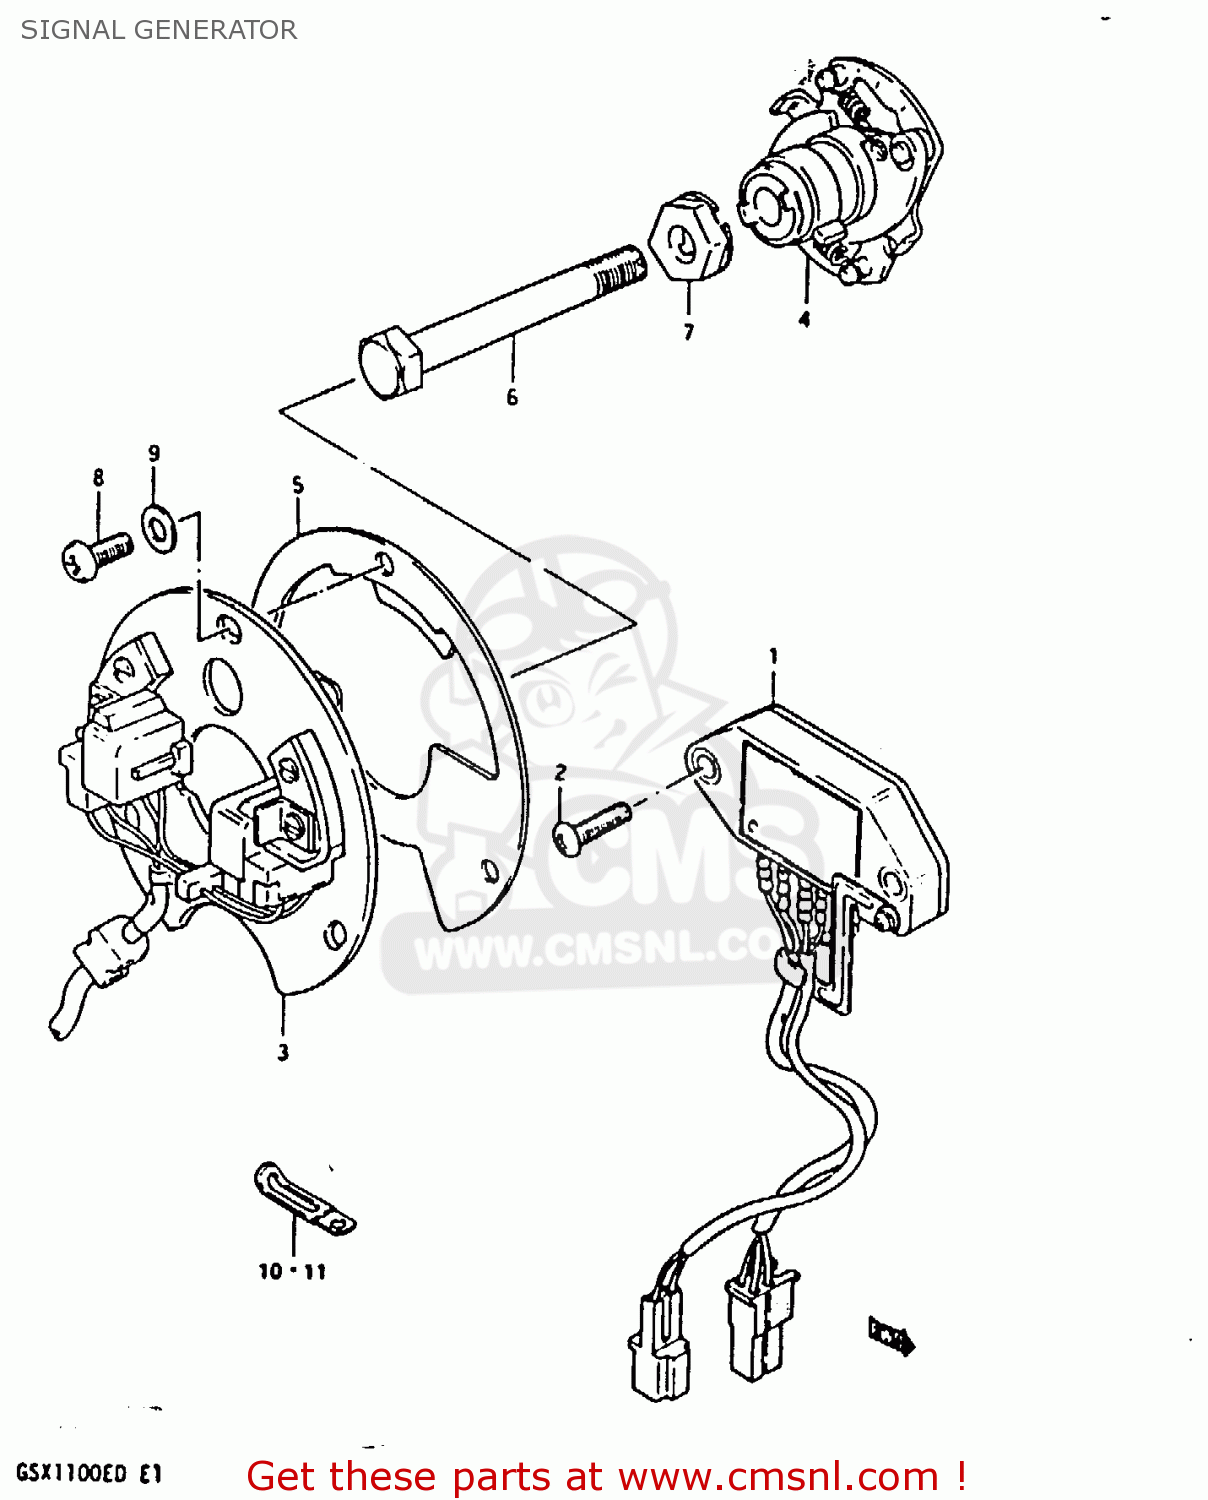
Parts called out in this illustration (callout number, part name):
1	IGNITER UNIT
2	SCREW
3	SIGNAL GENERATOR ASSEMBLY
4	GOVERNOR ASSEMBLY
5	PLATE,TIMING
6	BOLT
7	WASHER
8	SCREW(5X12)
9	WASHER
10	CLAMP L:35
11	CLAMP
